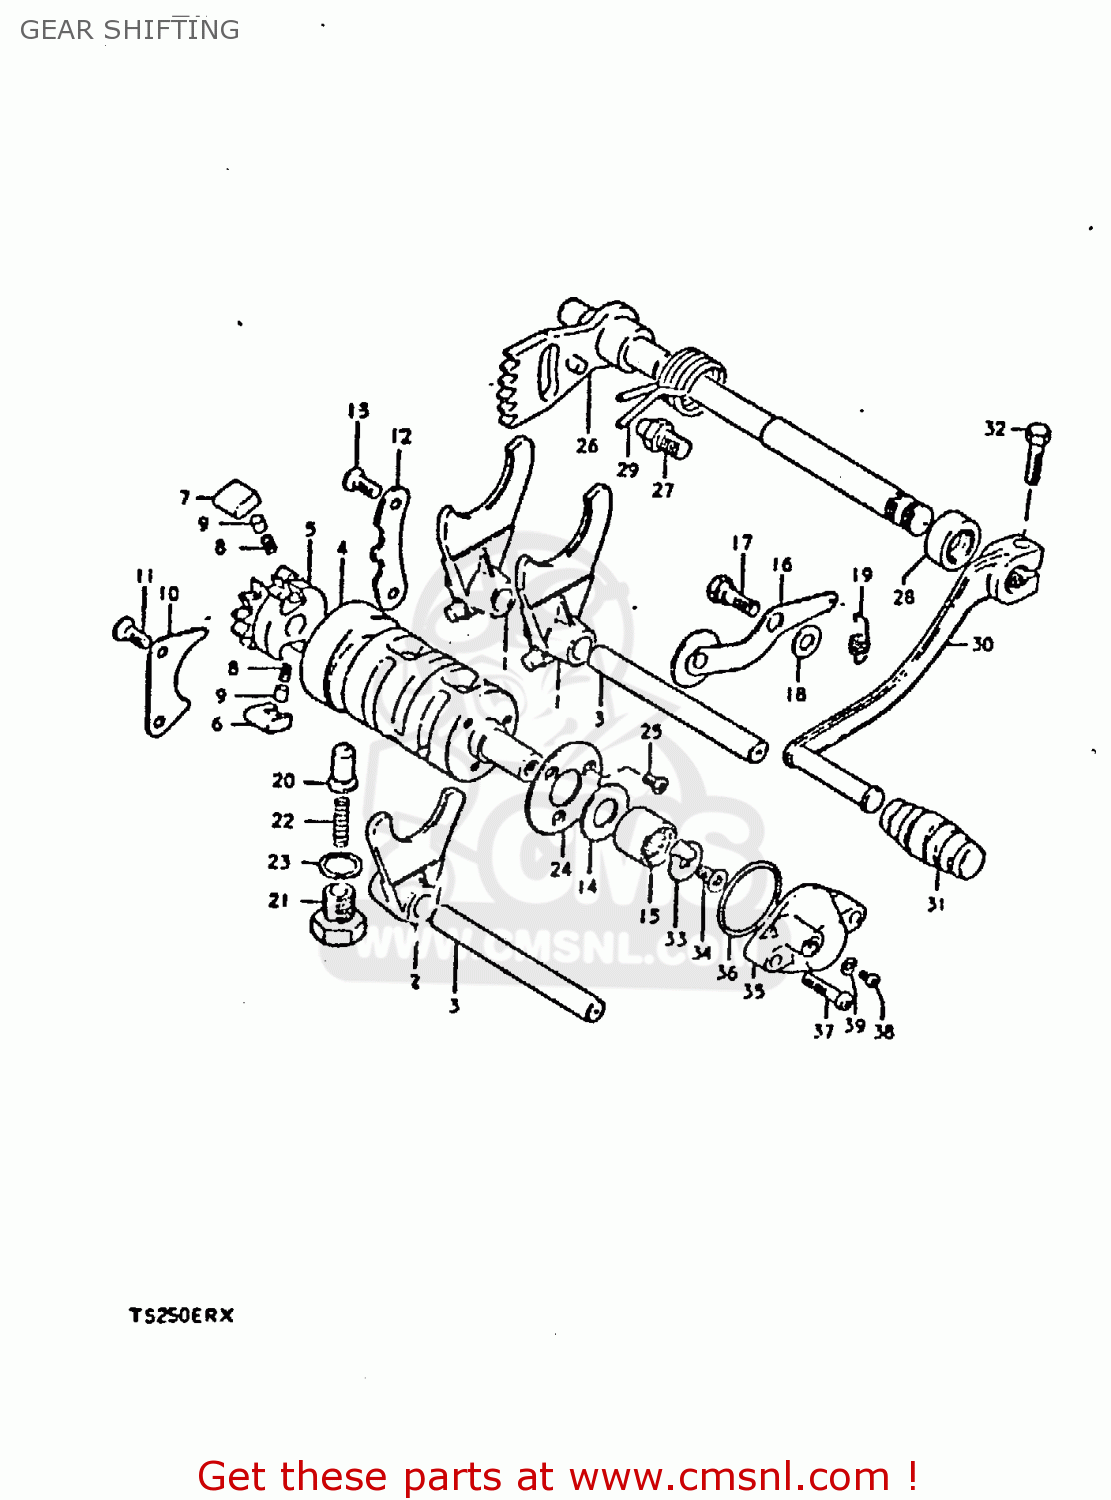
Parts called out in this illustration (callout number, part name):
1	FORK,GEAR SHIFT NO.1
2	FORK,GEAR SHIFT NO.3
3	SHAFT,GEAR SHIFT FORK
4	CAM,GEAR SHIFT
5	RETAINER,GEAR SHIFT CAM
6	PAWL,GEAR SHIFT NO.1
7	PAWL,GEAR SHIFT NO.2
8	SPRING
9	PIN(5X8)
10	LIFTER,GEAR SHIFT PAWL
11	SCREW
12	GUIDE,GEAR SHIFTING CABLE
13	SCREW
14	WASHER
15	ROLLER BEARING (12X18X1
16	STOPPER,GEAR SHIFTING
17	BOLT(6X16.1)
18	WASHER
19	SPRING
20	STOPPER,GEAR SHIFT CAM NO.2
21	HOLDER,GEAR SHIFT CAM STOP SPR
22	SPRING
23	GASKET(14X19.2X2) (NAS)
24	PLATE,GEAR SHIFT CAM STOPPER
25	SCREW 4X12
26	27
27	STOPPER,GEAR SHIFT CAM
28	OIL SEAL
29	SPRING
30	LEVER ASSY,GEAR SHIFT
31	RUBBER,GEAR SHIFT PEDAL
32	BOLT
33	CONTACT,GEAR SHIFT SWITCH
34	SCREW
35	BODY,GEAR SHIFT SWITCH
36	O RING(D:1.9,ID:27.7)
37	SCREW 5X20
38	SCREW
39	WASHER
